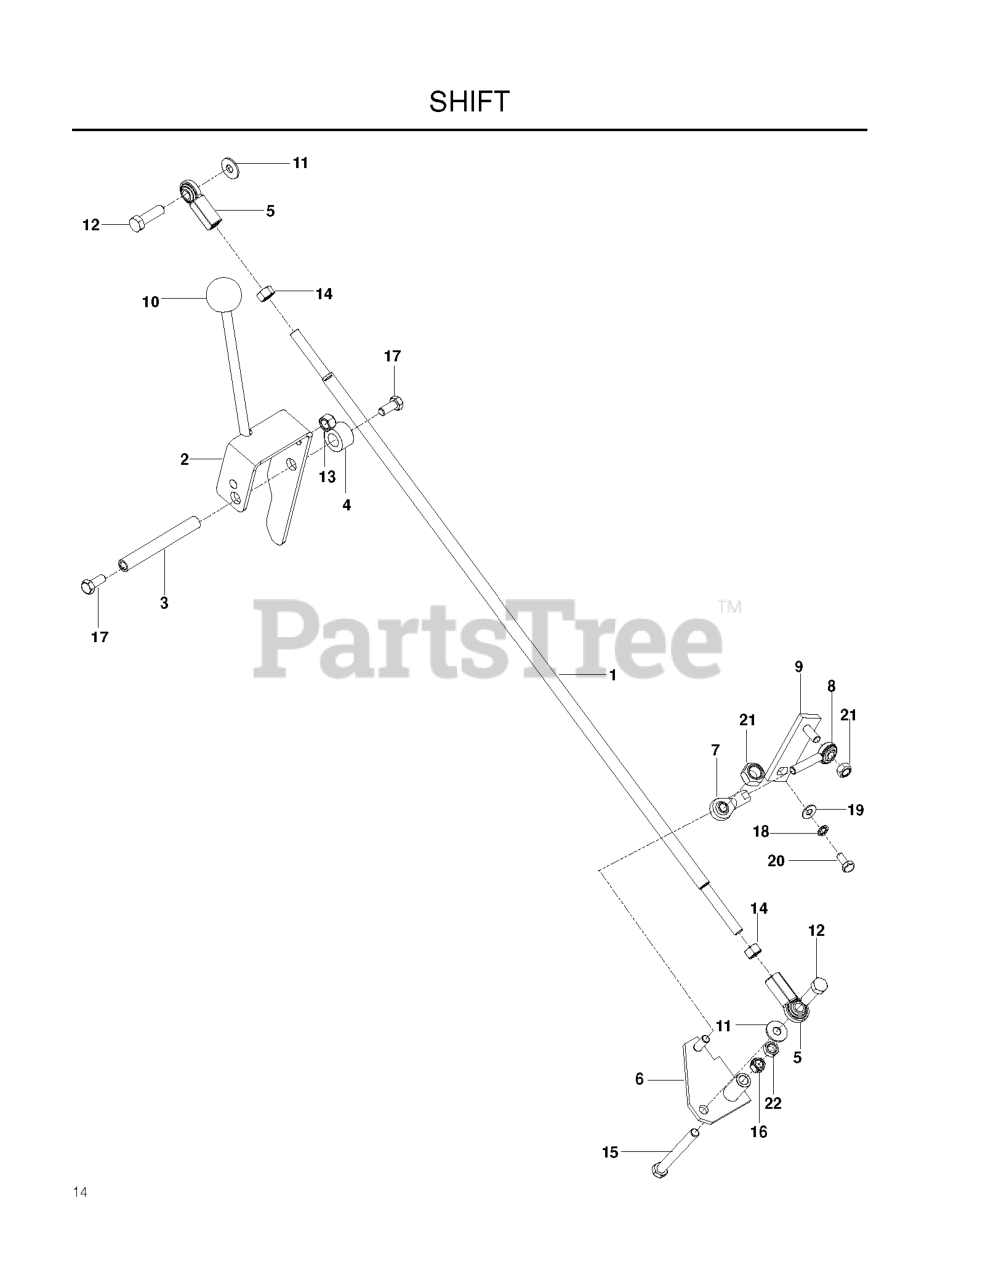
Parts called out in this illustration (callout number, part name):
1	SHIFT ROD, BLACK
2	SHIFT LEVER, ORANGE
3	SHAFT - SHIFT PIVOT
6	BELL CRANK SHIFT KIT
7	BALL JOINT, RIGHT HANDED
8	ROD END 5/16 MALE
9	KIT ARM TRANS SHIFT W/HDW
10	KNOB-SHIFT
11	WASHER 5/16 FLAT
12	HCS 3/8C X 1 1/4 GR5
13	NUT 3/8-16 NYLOC
15	HCS 3/8C X 3 1/2
16	NUT 3/8C CENTERBLOCK
17	HCS 5/16C X 3/4
18	WASHER 1/4 INT TOOTH
19	WASHER 1/4 SAE
20	HCS 1/4-28.X
21	NUT 5/16-24 TOP LK GRC ZD
22	NUT 3/8-16 HEX JAM
